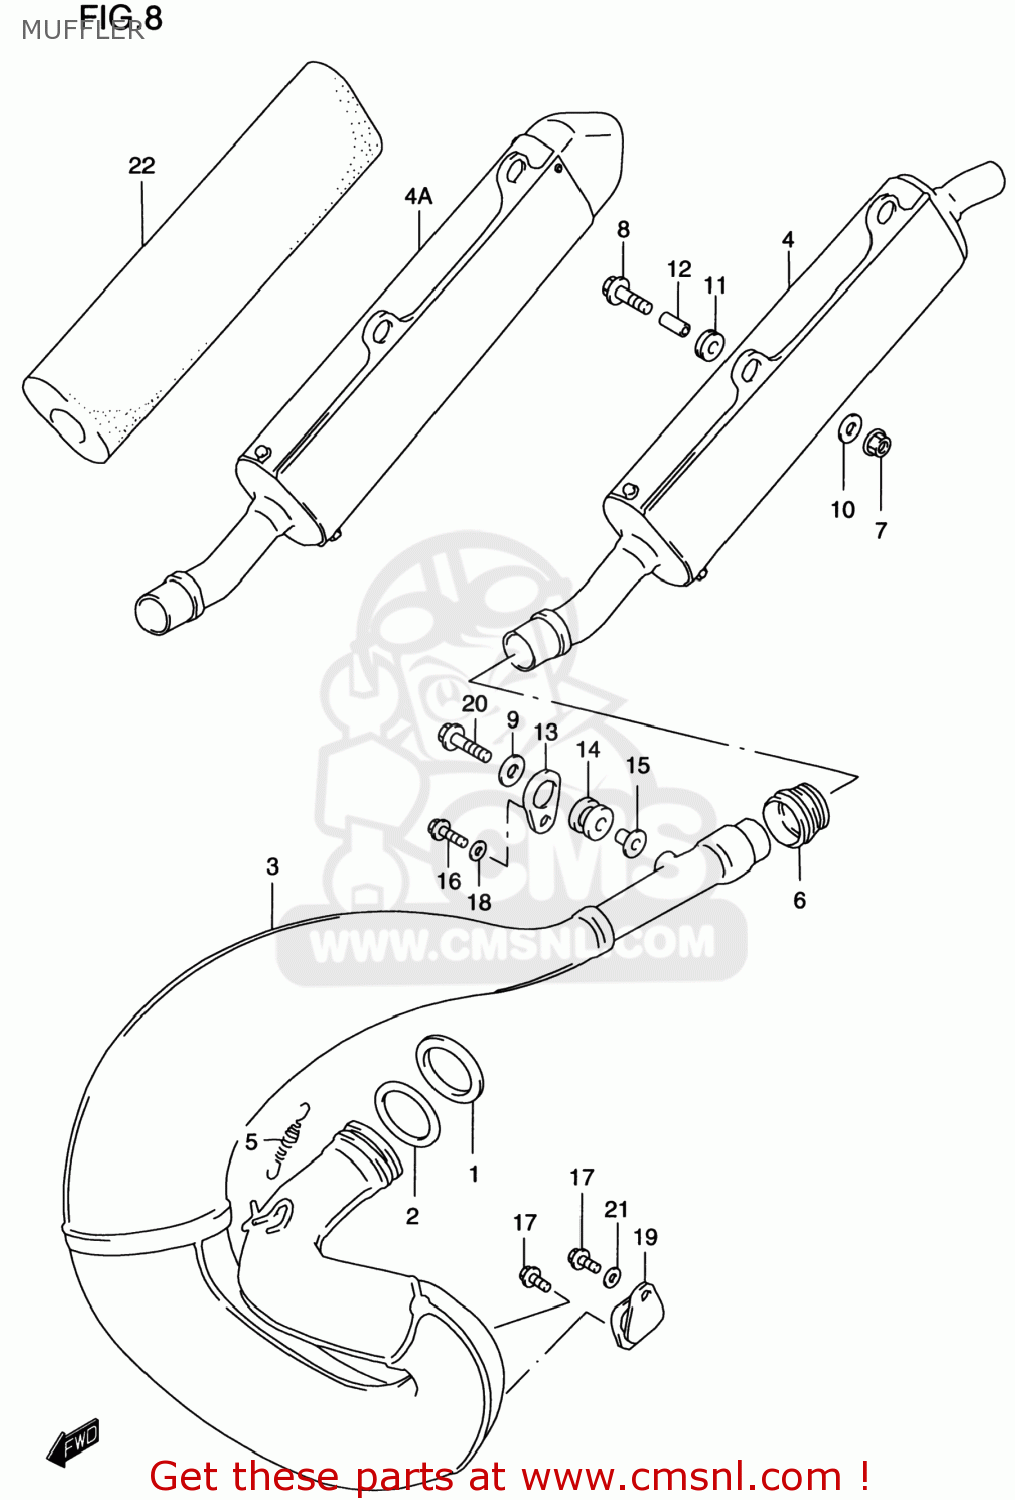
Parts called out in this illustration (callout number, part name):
1	WASHER,EXHAUST PIPE
2	O RING,EXHAUST PIPE
3	BODY,MUFFLER 1ST
4	BODY,MUFFLER,SECOND
4A	BODY,MUFFLER 2ND
5	SPRING
6	CONNECTOR,MUFFLER
7	NUT
8	BOLT,G/S SWITC
9	WASHER(6.5X24X1.2)
10	WASHER(6.5X24X1.2)
11	CUSHION
12	SPACER(6.5X11.5X12)
13	PLATE,MUFFLER MTG
14	CUSHION,MUFFLER
15	SPACER,MUF MTG
16	SCREW
17	BOLT
18	WASHER
19	DAMPER,MUFFLER SUPPORT
20	BOLT
21	WASHER
22	SILENCER,MUFFLER
